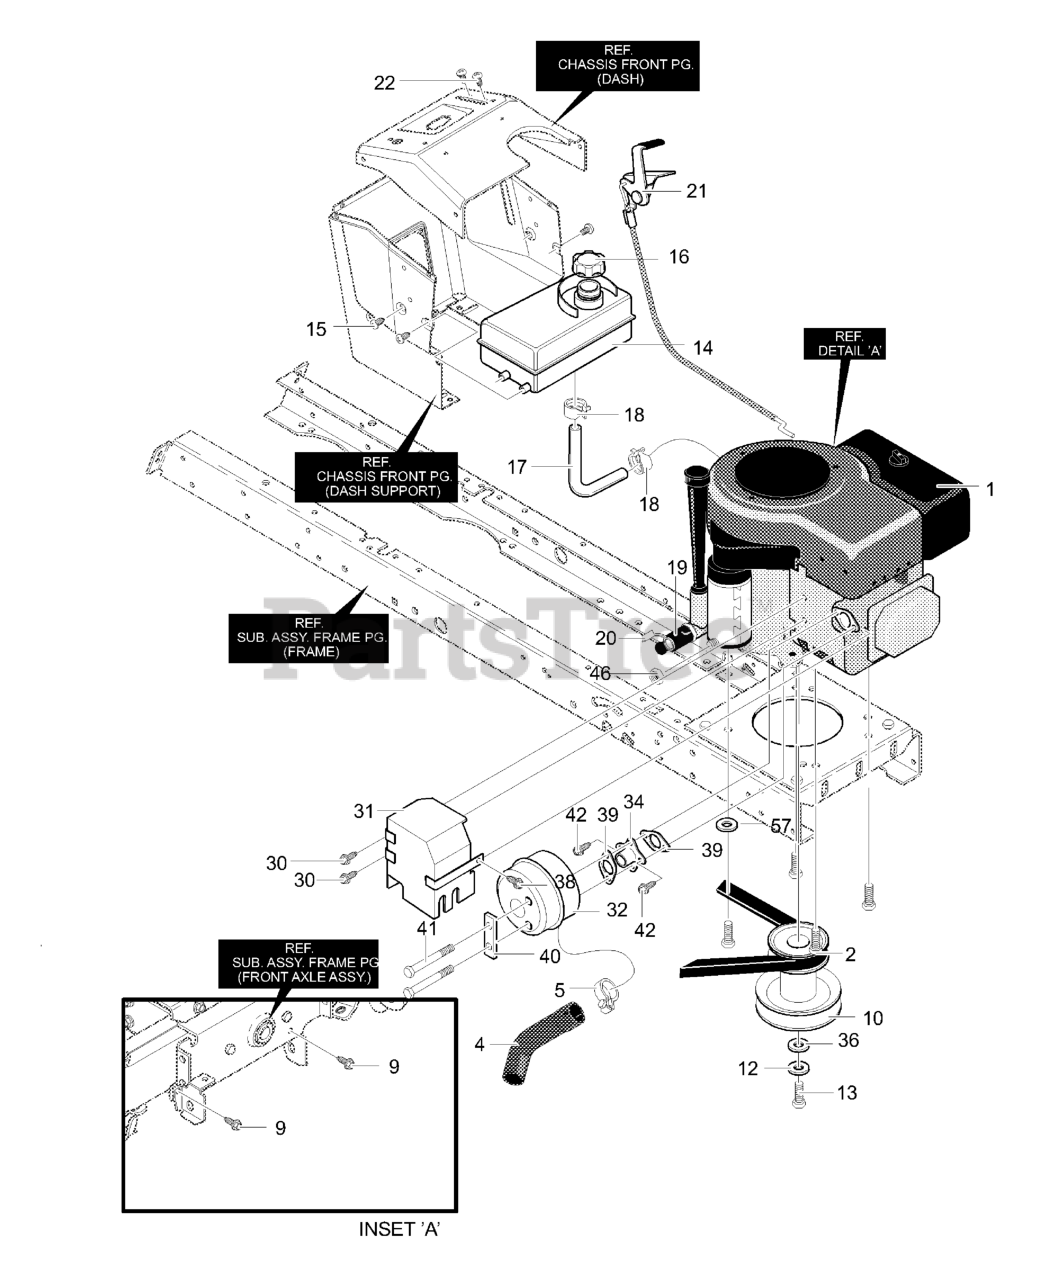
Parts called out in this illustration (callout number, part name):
1	Engine
2	Engine Bolt 3/8x1.25
5	GASKET, Exhaust
6	Shield, Heat
7	Screw, 5/16-18 x 4.125
9	Screw, 5/16-18 x 0.75
10	Stack Pulley
12	Washer, Regsptlk
13	Bolt, 7/16-20x1.75LG
14	TANK, Fuel 1.4 Gal.
15	Screw, 15TP
16	Fuel Cap
17	Tubing 14.50 Inches
18	Clamp, Fuel
19	Oil Drain Valve Assembly
20	Cap, Oil Drain Valve
21	Throttle Control
22	Screw, #8-16x.38
31	Muffler
32	Deflector, Exhaust
33	Screw, #8-32x.38
46	Nut, 1/4-20 Reghexjam
56	Washer, Flat
57	Washer, Exlk
